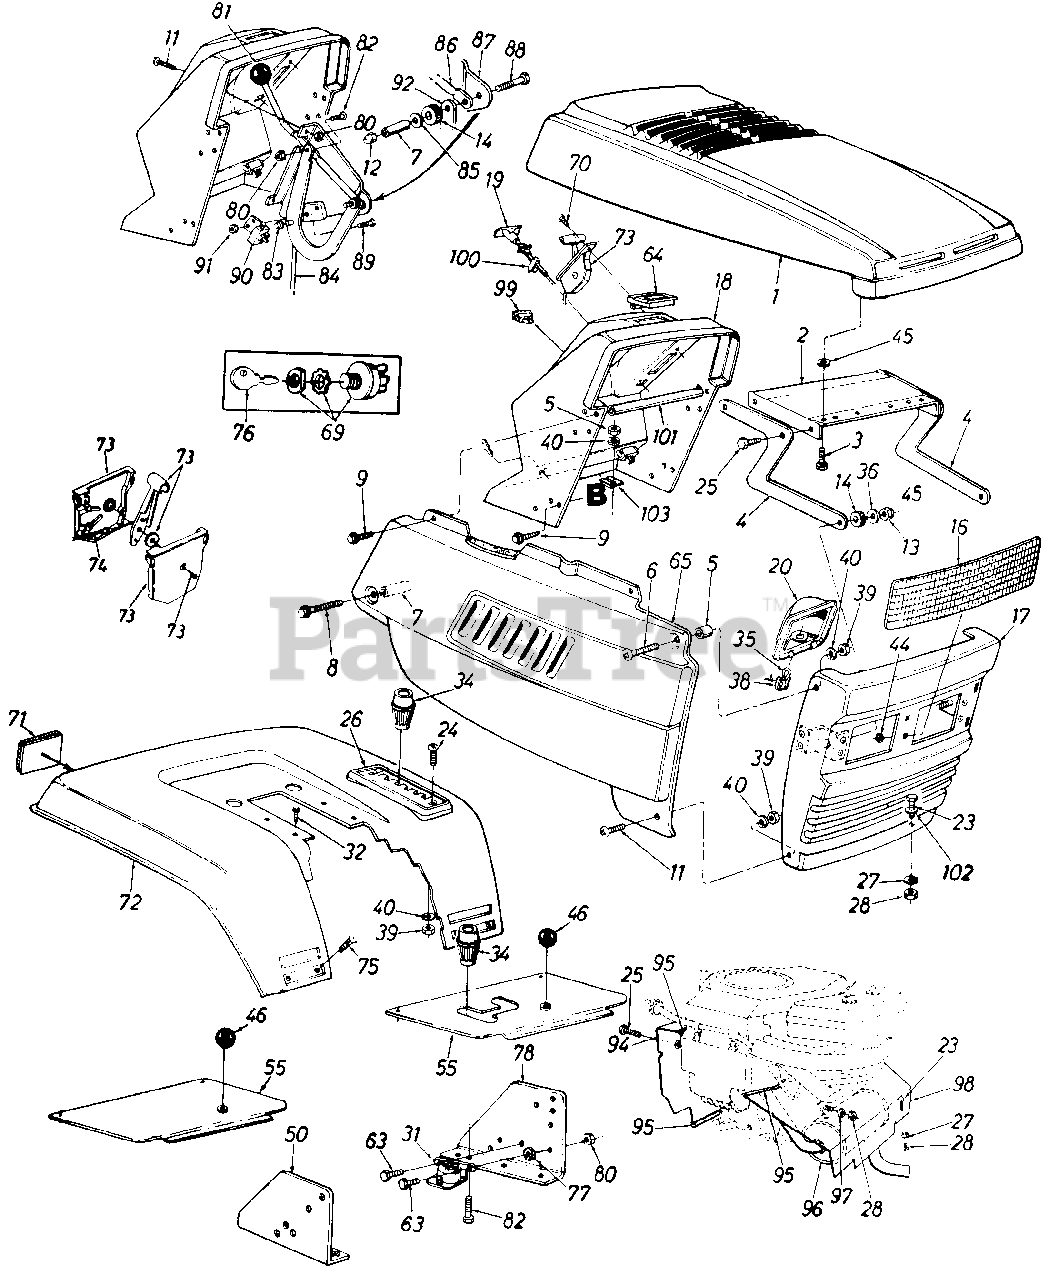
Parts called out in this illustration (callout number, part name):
4	Hood Hinge
5	Spacer .34" I.D. x .437"
6	Truss Hd. Mach. Scr. 1/4-20 Thd.
7	Spacer .26" I.D. x .375"
8	Hex Wash. TT-Tap Scr. 1/4-20 x 1.75" Lg.
9	Hex T-Tap Scr. 1/4-20 x .75" Lg.
11	Truss Mach. Scr. 1/4-20 x .5" Lg.
12	Hex Ins. L-Nut 1/4-20 Thd.
13	Hex L-Nut 5/16-18 Thd.
14	Rubber Washer
16	Headlight Lens
19	Choke Control
20	Headlight Housing
23	Hex Bolt 5/16-18 x .75" Lg.
24	Truss Mach. Scr. 1/4-20 x .75" Lg.
25	Hex Wash. Hd. Scr. 1/4" x .5" Lg.
26	6-Speed Selector Plate
27	L-Wash. 5/16" I.D.
28	Hex Nut 5/16-18 Thd.
31	Solenoid
32	Hex Hd. Rolling Scr. 5/16-24 x .75" Lg.
34	Shift Knob
35	Lamp
36	Bell-Wash. .34" I.D. x .87"
38	Socket
39	Hex Nut 1/4-20 Thd.
40	L-Wash. 1/4" I.D.
44	Speed Nut 5/16" I.D.
45	Fl-Wash. .406" I.D.
46	Ball Knob
63	Hex Bolt 1/4-20 x .5" Lg.
64	Ammeter
70	Truss Mach. AB-Tap Scr. #10 x .5" Lg.
71	Reflector
74	Throttle Control Wire 35" Lg.
75	Carriage Bolt 1/4-20 x .5" Lg.
76	Key
77	Ext. L-Wash. 1/4" I.D.
81	Ball Knob
82	Hex Bolt 1/4-20 x .62" Lg.
83	Push Nut
84	PTO Rod
85	Fl-Wash. .281" I.D. x .73"
86	PTO Lever
87	Deck Clutch Control Brkt.
88	Hex Bolt 1/4-20 x 2.5" Lg.
89	Truss Mach. Scr. #10-24 x .5" Lg.
90	Safety Switch
91	Hex Nut #10-24 Thd.
92	PTO Bracket
94	Engine Baffle
95	Trim Strip 10" Lg.
96	Muffler
97	Spec. L-Wash. 5/16" I.D.
98	Front Heat Shield
99	Light Switch
100	Retainer Clip
101	Dash Support Tube
102	Fl-Wash. .344" I.D. x 1" O.D.
103	Dash Panel Fastening Tab
